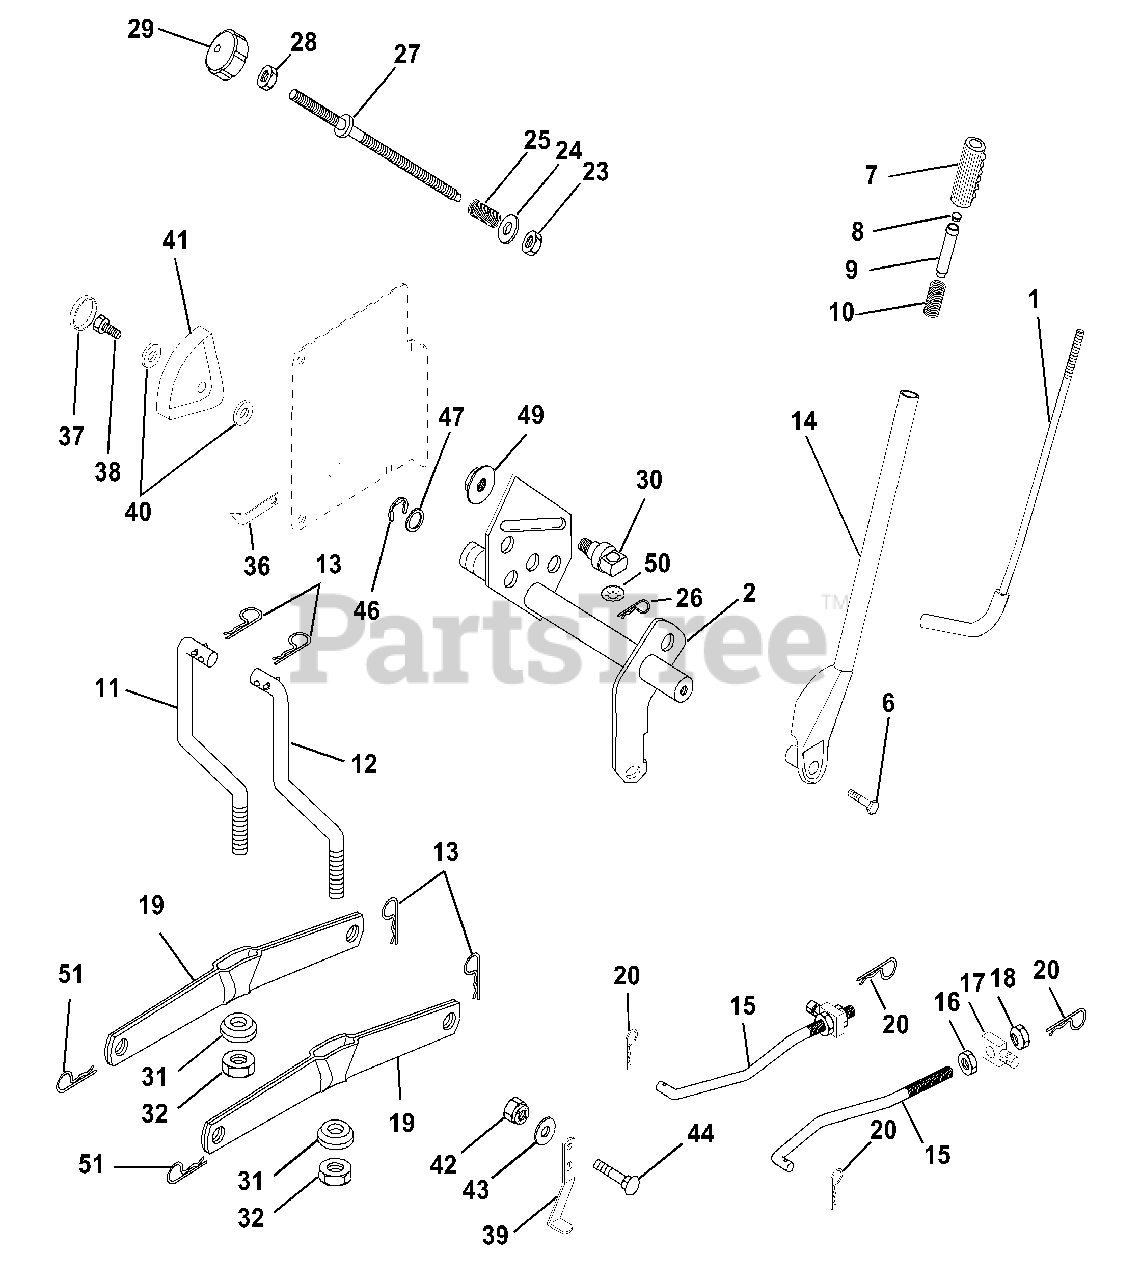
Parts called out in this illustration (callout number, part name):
1	Rod Assembly, Lever
2	Shaft Assembly, Lift
6	Bolt, Hex Head, Fin. 3/8-16 x 1-1/2
7	Grip Handle
8	Button Plunger Black
9	Plunger Lever Lift
10	Spring
11	Link, Lift, LH
12	Link, Lift, RH
13	Retainer Spring
14	Lever Assembly, Lift, RH
15	Link, Front
16	Nut, Hex, Jam 1/2-13 UNC
17	Trunnion
18	Nut Crownlock 1/2-13 Unc
19	Arm, Suspension, Rear
20	Retainer Spring
23	Nut, Special
24	Washer 13/32 x 5/8 x 16 Gauge
25	Spring
26	Retainer Clip
27	Adjustment Rod, Lift
28	Nut, Hex, Jam 3/8-16 UNC
29	Knob, Infinite Height Adjustment
30	Trunnion, Inf. Height
31	Bearing
32	Nut, Crownlock 3/8-24
36	Pointer Height Indicator
37	Plug Hole Blk 1.485/1.515 Dia.
38	Screw 5/16-18 x 1 Smgml Tap/R
39	Stop Over Center
40	Washer 11/32 x 1-1/2 10 Ga.
41	Scale Ind. Height Blk.
42	Nut, Crownlock 3/8-16 UNC
43	Washer 13/32 x 1 x 12 Ga.
44	Bolt, Carriage 3/8-16 x 1.00
47	Washer
49	Nut Hex Flange Lock
50	Nut Push Phos & Oil
51	Retainer Spring
